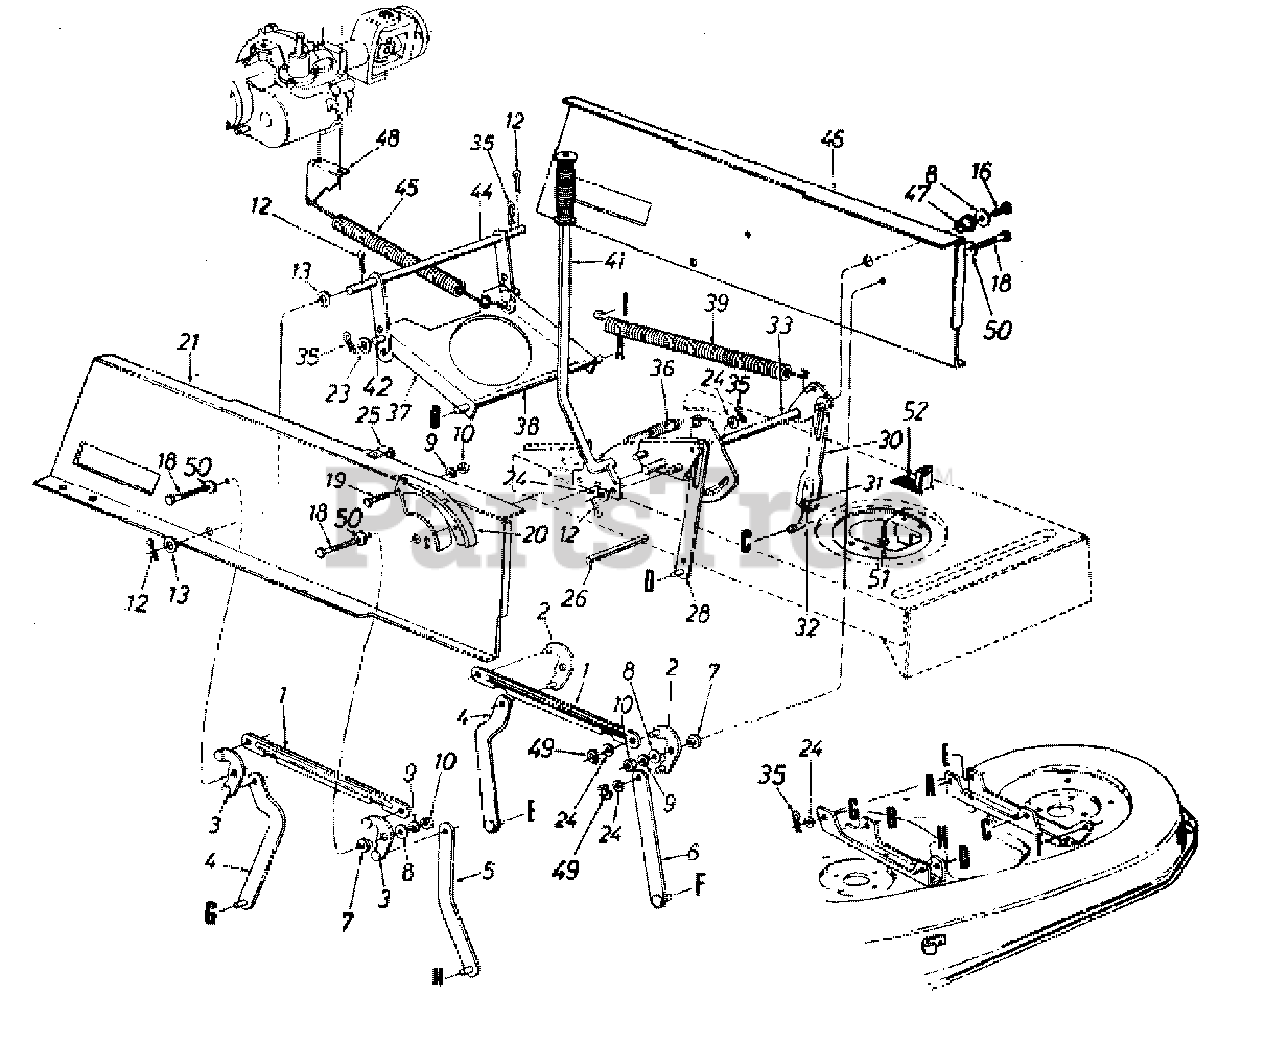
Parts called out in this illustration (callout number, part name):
3	Pivot Link Ass'y.-R.H.
7	Shld. Spacer .318" I.D.
8	Fl-Wash. .344" I.D. x .62" O.D.
9	L-Wash. 5/16" I.D.
10	Sems Nut 1/4-20 Thd.
12	Cotter Pin 1/8" Dia.
13	Fl-Wash. .635" I.D. x 1.0" O.D.
16	Hex Wash. TT-Tap Scr. 5/16-18 x .75" Lg.
18	Hex Wash. Hd. Scr. 5/16-18 x .875" Lg.
19	Hex Bolt 5/16-18 x .75" Lg.
21	Upper Frame-R.H.
23	Fl-Wash. .385" I.D. x .87" O.D.
24	Fl-Wash. .531" I.D. x .93" O.D.
26	Running Board Rod
31	Hex Nut 1/2-20 Thd. (Gr. 5)
32	Lift Link Adjuster
33	Lift Shaft Ass'y.
35	Inter. Cotter Pin 3/8" Dia.
36	Extension Spring
39	Extension Spring
46	Upper Frame-L.H.
47	Flange Brg. .632" I.D.
49	"E"-Ring
50	Bell-Wash. .325" I.D.
51	Hex Wash. Hd. TT-Tap Scr. 1/4-20 x .5" Lg.
52	Spring Switch
